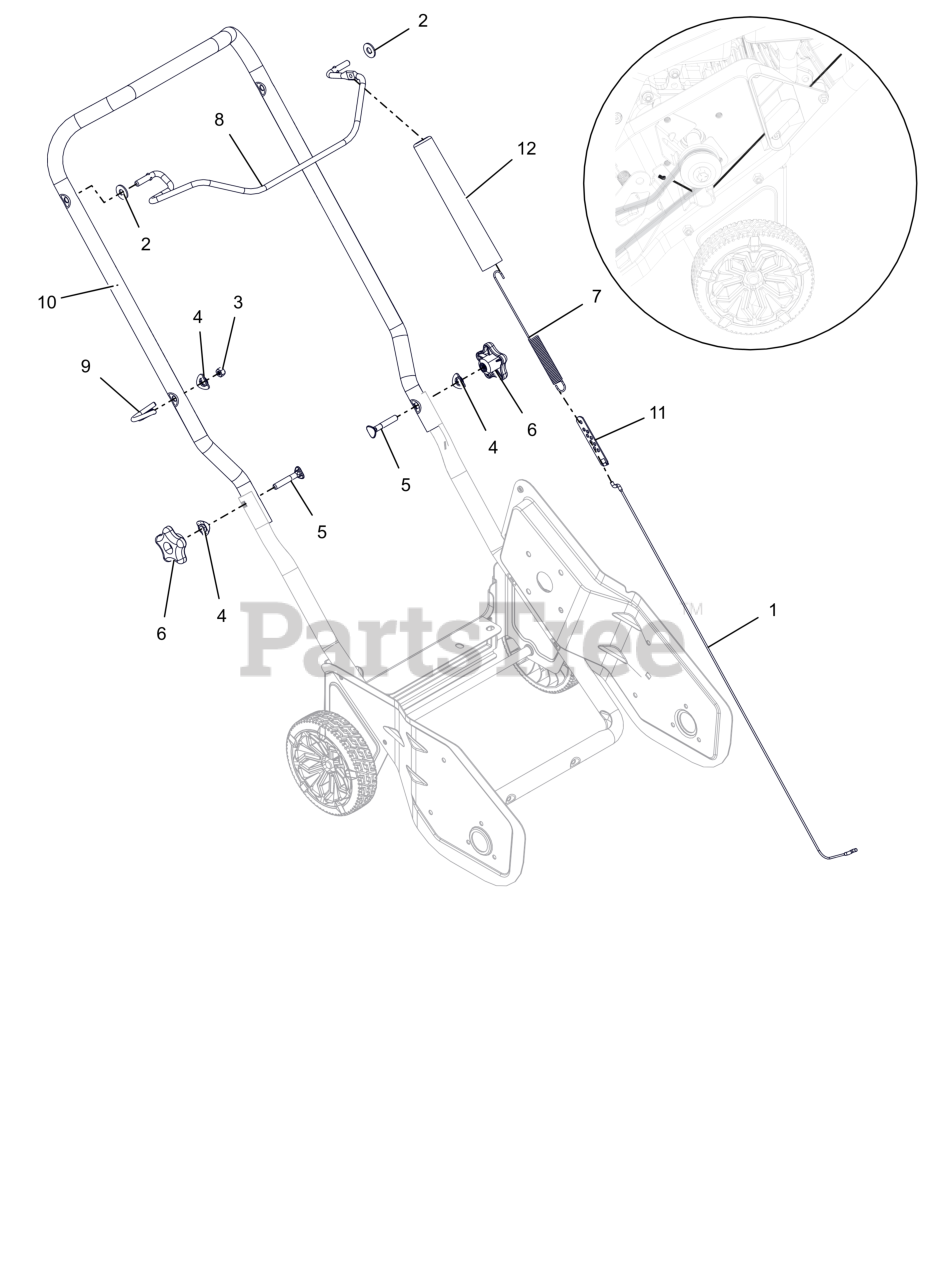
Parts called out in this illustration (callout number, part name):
1	CABLE, AUGER
2	WSHR, FLAT .375X.875X.065 (BLACK)
3	NUT, NYLON .250 - 20 (BLACK)
4	WSHR, HANDLEBAR - 5/16
5	.312-18 X 2 HANDLE BAR SCREW
6	.321-18 KNOB
7	SPRG, OPC
8	HANDLE, BAIL
9	GUIDE, RECOIL ROPE
10	KIT, UPPER HANDLEBAR W/DECAL
11	ADJUSTER, OPC
12	COVER, OPC SPRING
